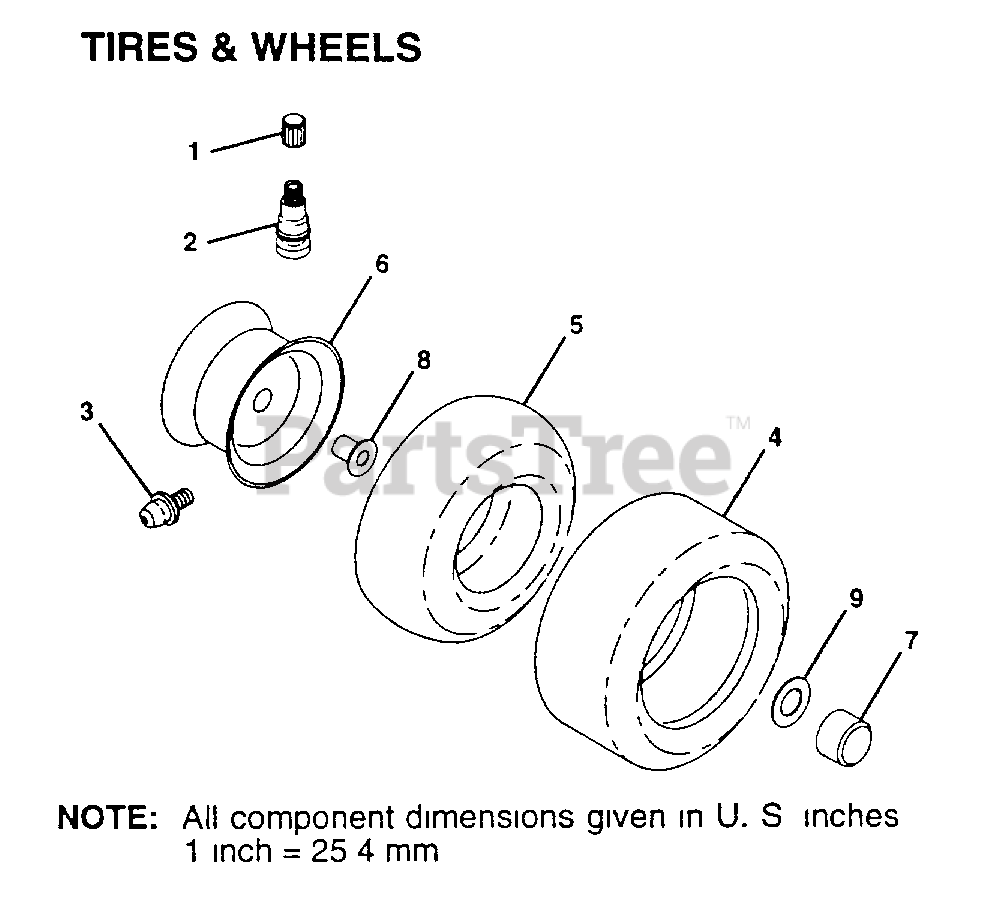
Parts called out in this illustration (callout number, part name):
1	VALVE CAP
2	VALVE STEM LT
3	FITTING LT
5	TUBE.5.3/4.5/6
5	TUBE.16X6.5/7.5-8
6	"RIM FRONT 6"""
6	"RIM ASM REAR 8"""
7	HUB CAP
8	"FLANGE, BEARING"
9	WASHER
